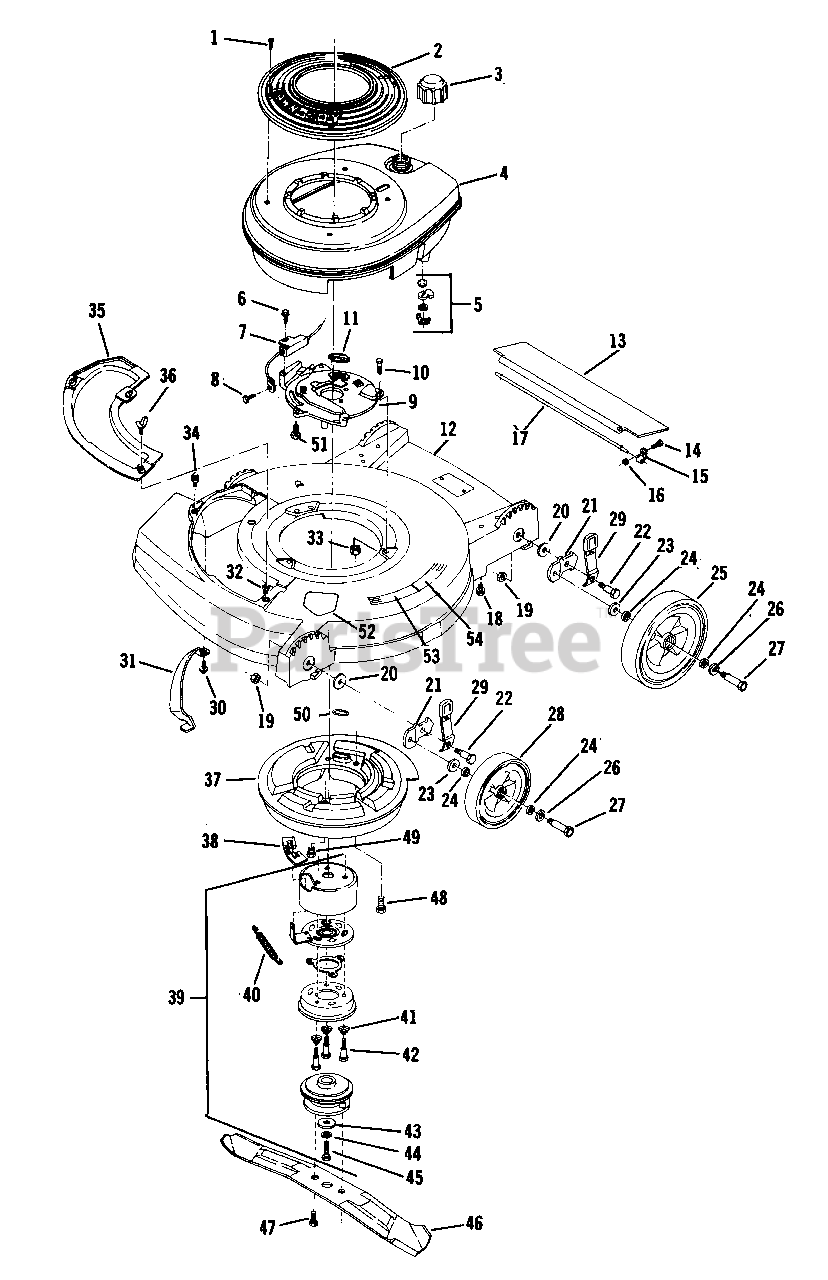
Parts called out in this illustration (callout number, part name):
1	Screw
2	Cover-Shroud
3	Fuel Cap
4	Shroud
5	Fuel Shut-Off Assembly
6	Screw
7	Control Cable Assembly
8	Bolt-Shoulder
9	Plate-Engine Mtg.
10	Screw-Eng. Mtg. Plate to Housing
11	Gasket-Exhaust
12	Housing-21" Push
13	Shield-Trailing
14	Screw
15	Clamp
16	Nut
17	Rod-Trailing Shield
18	Screw-Handle Brkt. to Housing
19	Nut
20	Washer
21	Bracket-Whl. Hgt. Adj.
22	Bolt-Shoulder
23	Washer
24	Washer-Felt
25	Wheel-Rear
26	Washer
27	Bolt-Wheel
28	Wheel-Front
29	Knob and Spring Assembly
30	Screw
31	Toe Bar
32	Grommet
33	Nut-Eng. Mtg. Plt. to Hsg.
34	Screw-Plate and Chute Mtg.
35	Cover-Chute
36	Wing Screw
37	Muffler Assembly
38	Shield-Actuator
39	Clutch Brake Assembly
40	Spring
41	Spring Pressure
42	Screw-Shoulder
43	Washer
44	Lockwasher
45	Screw-Socket Head
46	Blade-21"
47	Screw-Sems-Blade
48	Screw-Muff. to Block
49	Screw-Muffler to Engine Mounting Plate
50	Seal-Exhaust
51	Screw-Engine Mounting Plate to Block
52	Decal-Blade Contact Warning
53	Starting Pad
54	Decal
